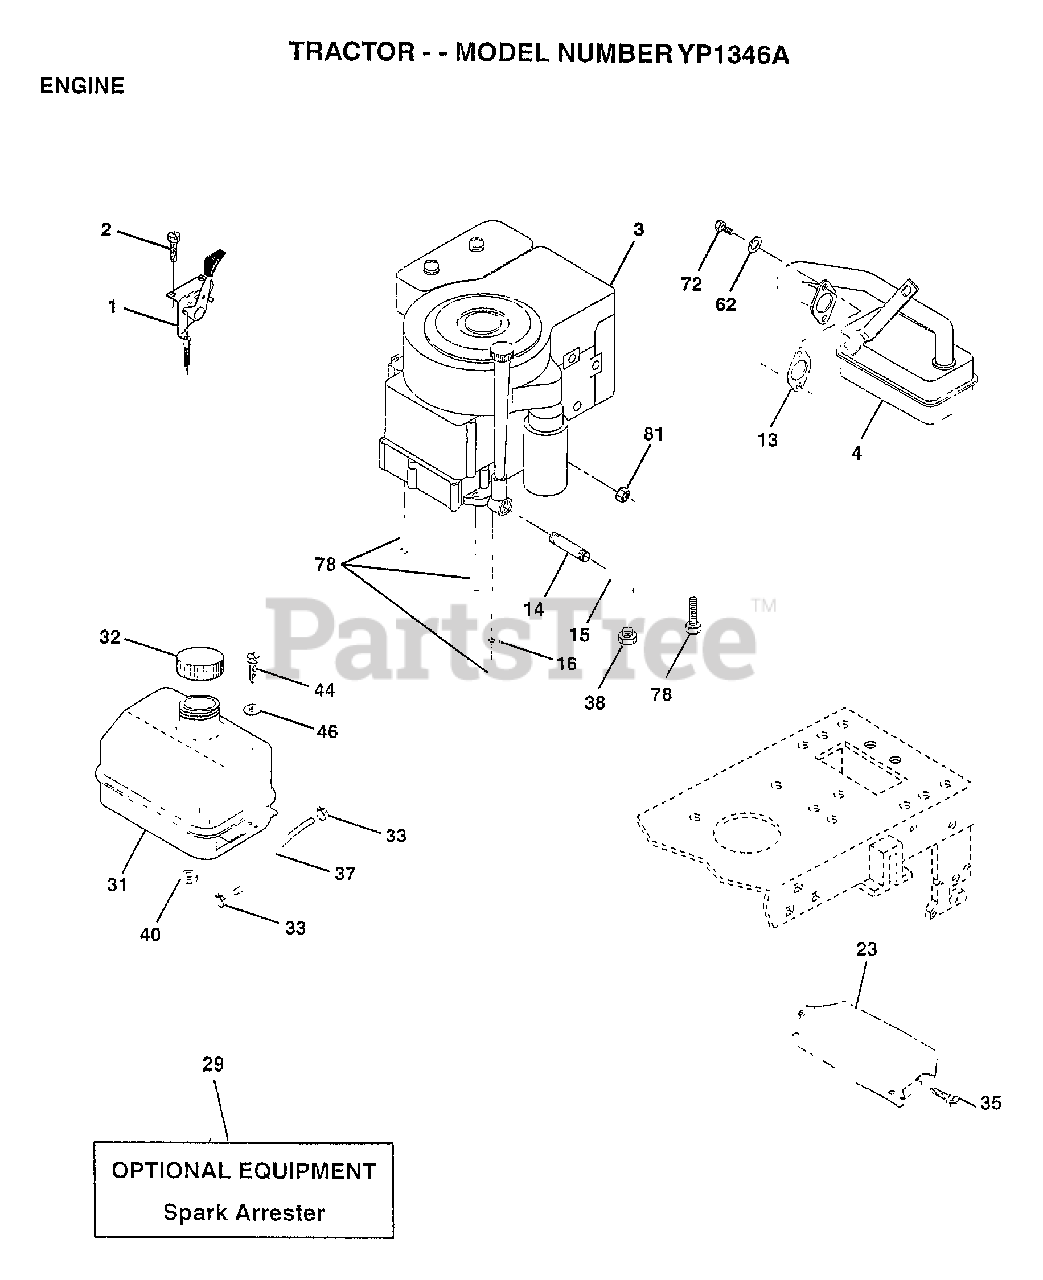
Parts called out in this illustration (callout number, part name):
1	CONTROL THROTTLE
2	SCREW LT
3	ENGINE, B&S 12HP
4	MUFFLER
13	GASKET ENG 1 313 LD TIN PLATED
14	PIPE NIPPLE
15	ELBOW
16	LOCKWASHER
23	SHIELD-HEAT
31	TANK.FUEL.LT.
32	CAP ASM FUEL
33	HOSE CLAMP
35	SCREW
37	LINE FUEL
44	SCREW HEX CRT
46	WASHER
62	LOCKWASHER
72	SCREW
78	SCREW
81	NUT
